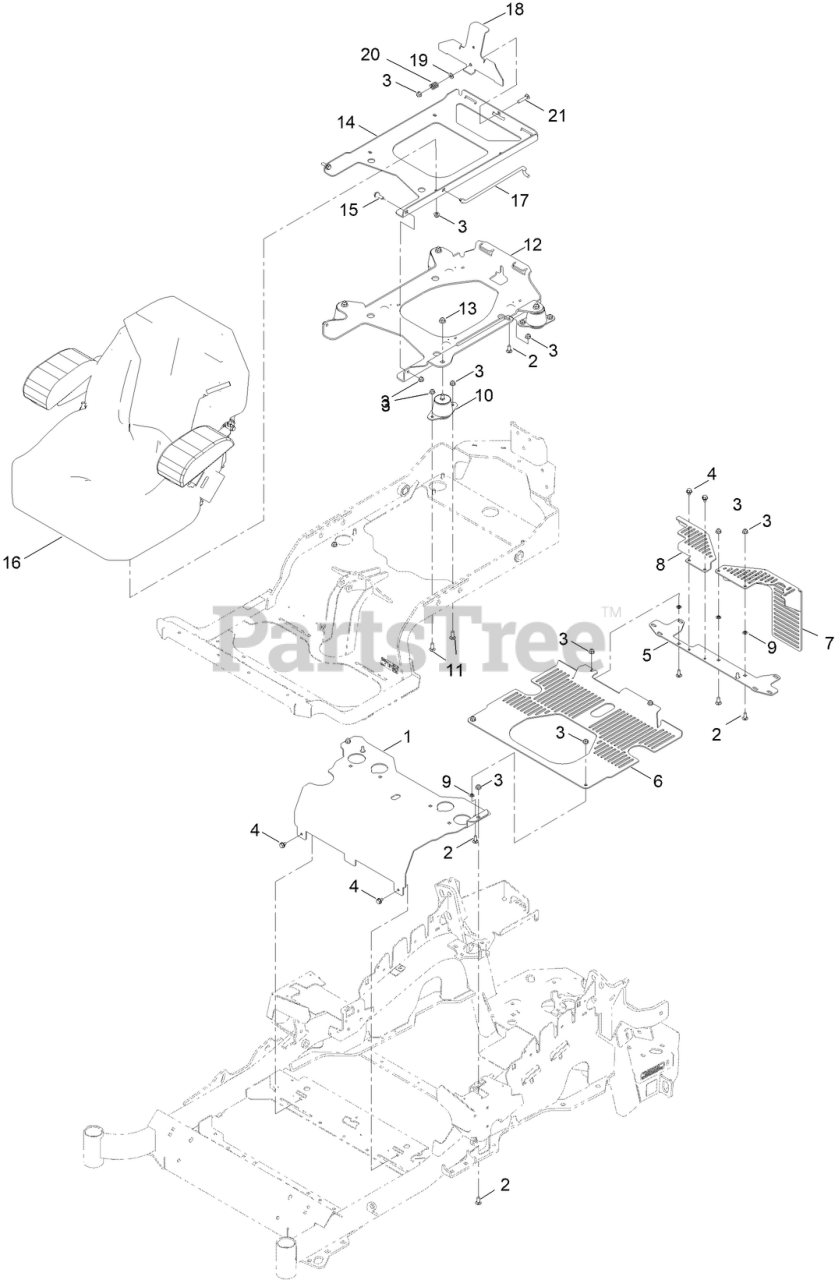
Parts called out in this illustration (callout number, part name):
1	PANEL-FRONT, SEAT MOUNT
2	SCREW-CARR
3	NUT-HF, NI
4	SCREW
5	PLATE-MOUNTING
6	GUARD-HYDRO
7	GUARD-HYDRO, LEFT REAR
8	GUARD-HYDRO, RIGHT REAR
9	RING-RETAINING, BOLT
10	ISOLATOR-SEAT
11	BOLT-CARR
12	PLATE-SUPPORT, ISO SEAT
13	NUT-HF, NI
14	PLATE-FRAME, SEAT
15	SCREW-SHOULDER
16	SEAT-STANDARD
17	ROD-PROP
18	PLATE-LATCH,SEAT
19	WASHER-PLAIN
20	SPRING-COMPRESSION
21	BOLT-CARR
